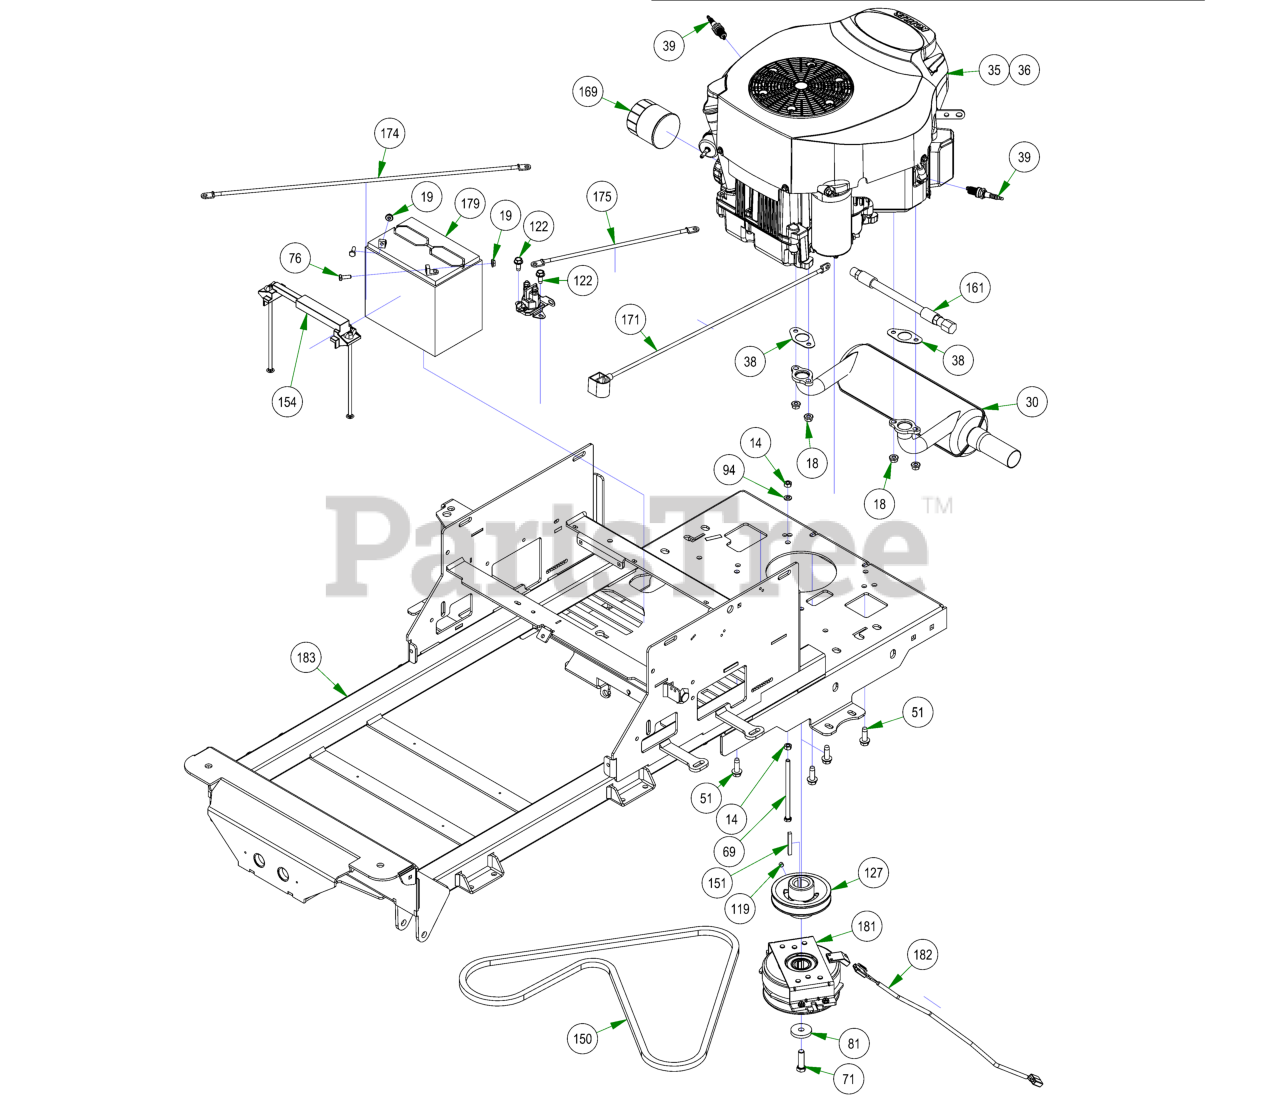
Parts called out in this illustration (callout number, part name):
14	5/16-18 HEX NUT ZINC
18	M8 Nut Connects the 015-1012-00 and the 015-8240-00
19	1/4-20 HEX SERRATED FLANGE NUT HARD/ZINC
30	Kohler Muffler
35	Kohler-2014 ZT 725cc
36	26hp Kohler-2018 ZT-KT745-3088
38	Exhaust Gasket
39	Spark Plug
51	3/8-16 X 1-1/8HEX WASHER UNSLOT SERRATED (TRI-LOB) TRS
69	5/16-18 X 5-1/2 HEX CAP SCREW (GR.5) ZINC
71	7/16-20 X 1-1/2 HEX CAP SCREW (GR.8) w/ Patch
76	1/4-20 X 3/4 HEX CAP SCREW (GR.5) ZINC
81	CLUTCH WASHER
94	5/16 SPLIT LOCKWASHER ZINC
119	5/16-24 X 1/4 SOCKET SET SCREW (CUP PT) PLAIN
122	5/16-18 X 3/4HEX WASHER SLOT (F) TCS ZINC
127	4 3/4 Motor Pulley
151	1/4 X 2 SQ MACHINERY KEY 1018 STL PLAIN
154	Hold Down Assembly
161	Oil drain Hose
169	25 HP Kohler Oil Filter ZT?MZ
170	Universal Inline Fuel Filter
171	24 inch Black Cable – MZ/ZT
174	24" Red Battery Cable
175	12 in red battery cable
179	SP-35 Battery
182	Clutch Pigtail
183	2022 Suspension ZT Frame - Painted
